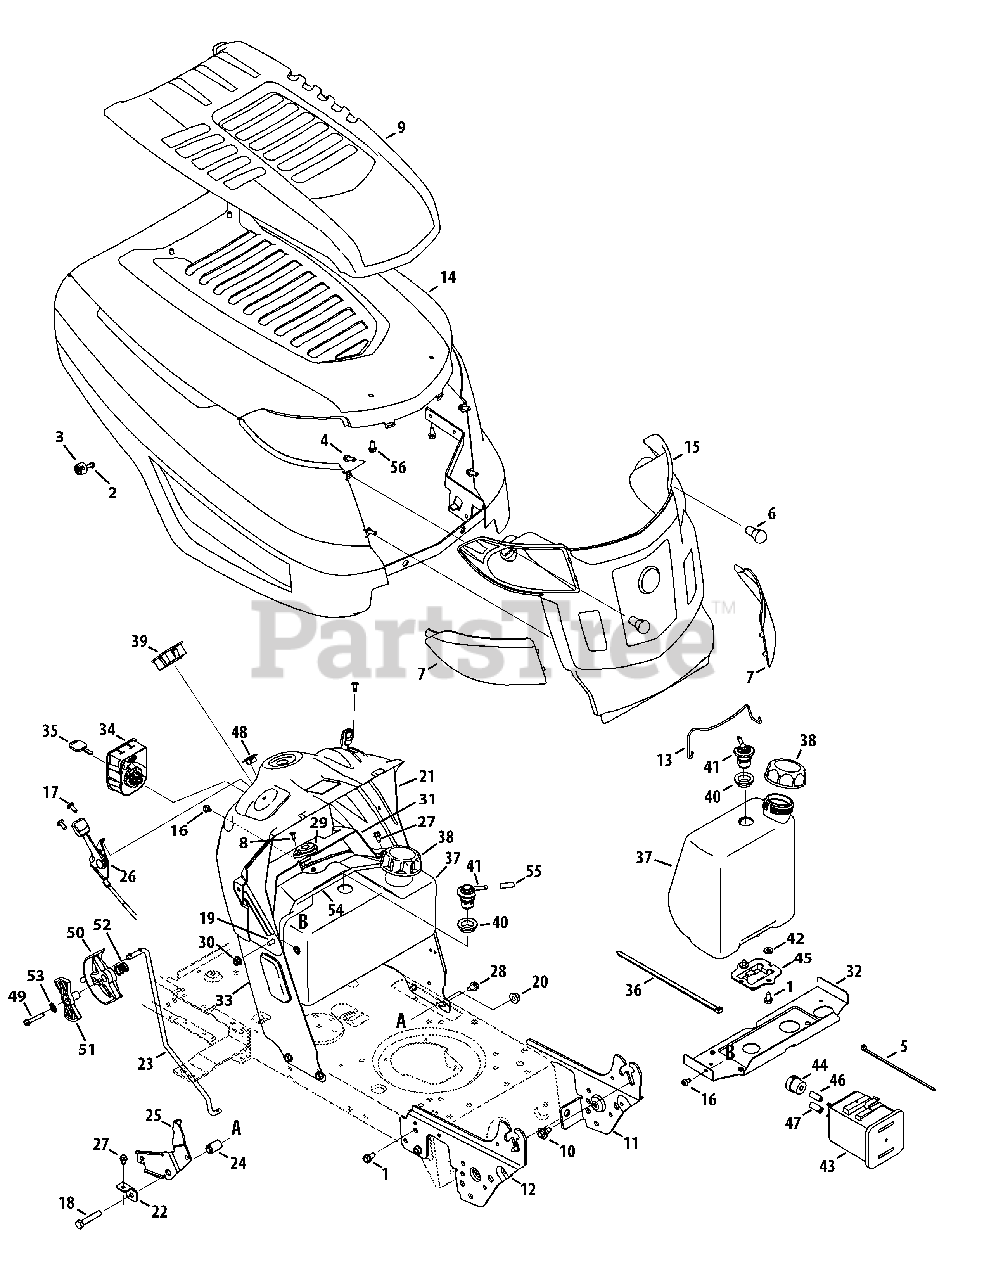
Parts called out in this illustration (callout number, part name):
1	Screw 5/16-18 x .750
2	Screw, #12-16 x 1.25
3	K-Style Bumper
4	Screw, 1/4 x .750
5	Cable Tie
6	Miniature lamp 12V socket
7	Grill Lens - LH
7	Grill Lens - RH
8	Screw, #10-16 x .500
10	Shoulder Screw .43 x .29
11	Suppport Bracket LH
12	Suppport Bracket RH
14	Hood, w/ scoop
16	Screw, 1/4-20 x .500
17	Screw 1/4-20 x .500
18	Hex Screw 3/8-16 x 2.00
19	Hex Screw, 5/16-18 x .625
20	Flange Lock Nut 3/8-16
21	Dash, Upper
22	Speed Latch Tab
23	Speed Control Rod
24	Flange Spacer .39 x .671 x 1.095
25	Transmission Speed Latch
26	Throttle/Choke Control Cable
27	Tap Screw, 1/4-20, 0.625
28	Screw 5/16-18 x .625
29	Bearing, .628 ID x 1.36
30	Flange lock Nut 5/16-18
31	Bracket, Steering Support
32	Gas Tank Support Bracket
33	Dash, Lower NOWDO
33	Dash, Lower WDO
34	Key Switch Module
35	Key, Assembly
36	Cable Tie
37	Fuel Tank, 2 Gallons, EPA
37	Fuel Tank, 1.36 Gallon, CARB
38	Fuel Cap
38	Fuel Cap, CARB
39	Ammeter Monitor Indicator
40	Rubber Grommet
41	Rollover Valve
42	Washer, Flat, .344 x .750 x .120
43	Canister, Carbon, 5 Gallon
44	Filter, Vent, Canister
45	Bracket., Adapter, Canister
46	Hose, Fuel, Low Perm., White
47	Hose, Fuel, Low Perm., Yellow
48	Choke Plug
49	Hex Washer Screw, 1/4-20 x 1.50
50	Shift Lever
51	Index Control
52	Compr. Spring, .685 OD x .63
53	Lock Washer, 1/4
54	Fuel Tank Clamp Rod
55	Hose Vent, 3/16 EPA
56	Screw, 1/4-15 x 0.50
